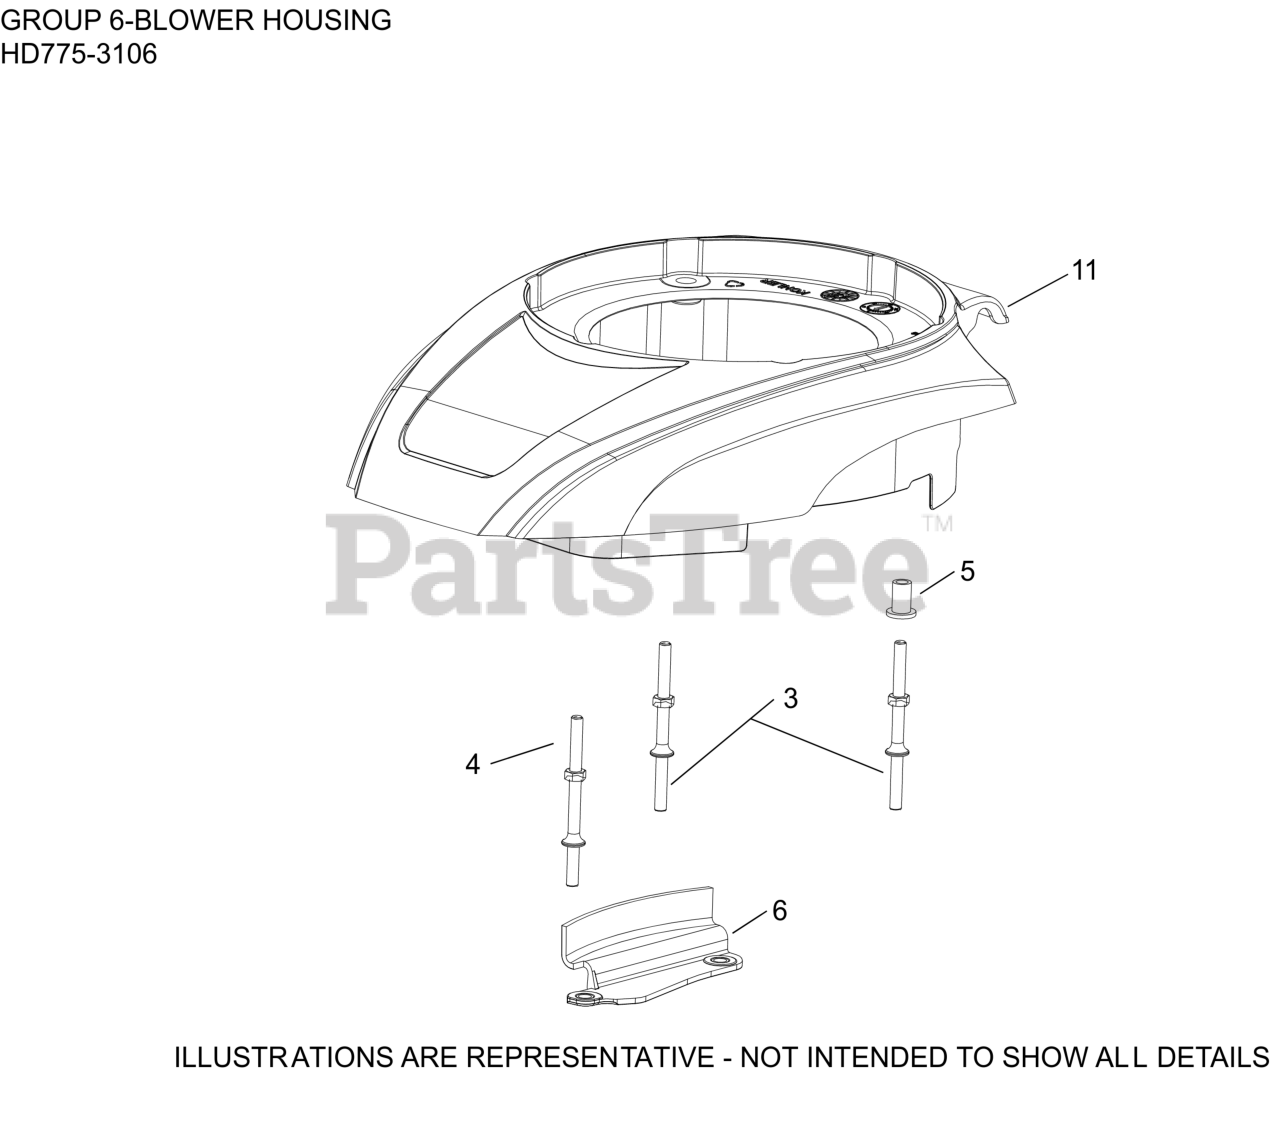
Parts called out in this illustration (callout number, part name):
3	STUD-USE 14 072 25-S
4	STUD-USE 14 072 26-S
6	NUT, HEX FLANGE (M6) - USE 14 100 16-S
6	GUARD, FINGER
11	COVER, ENGINE
